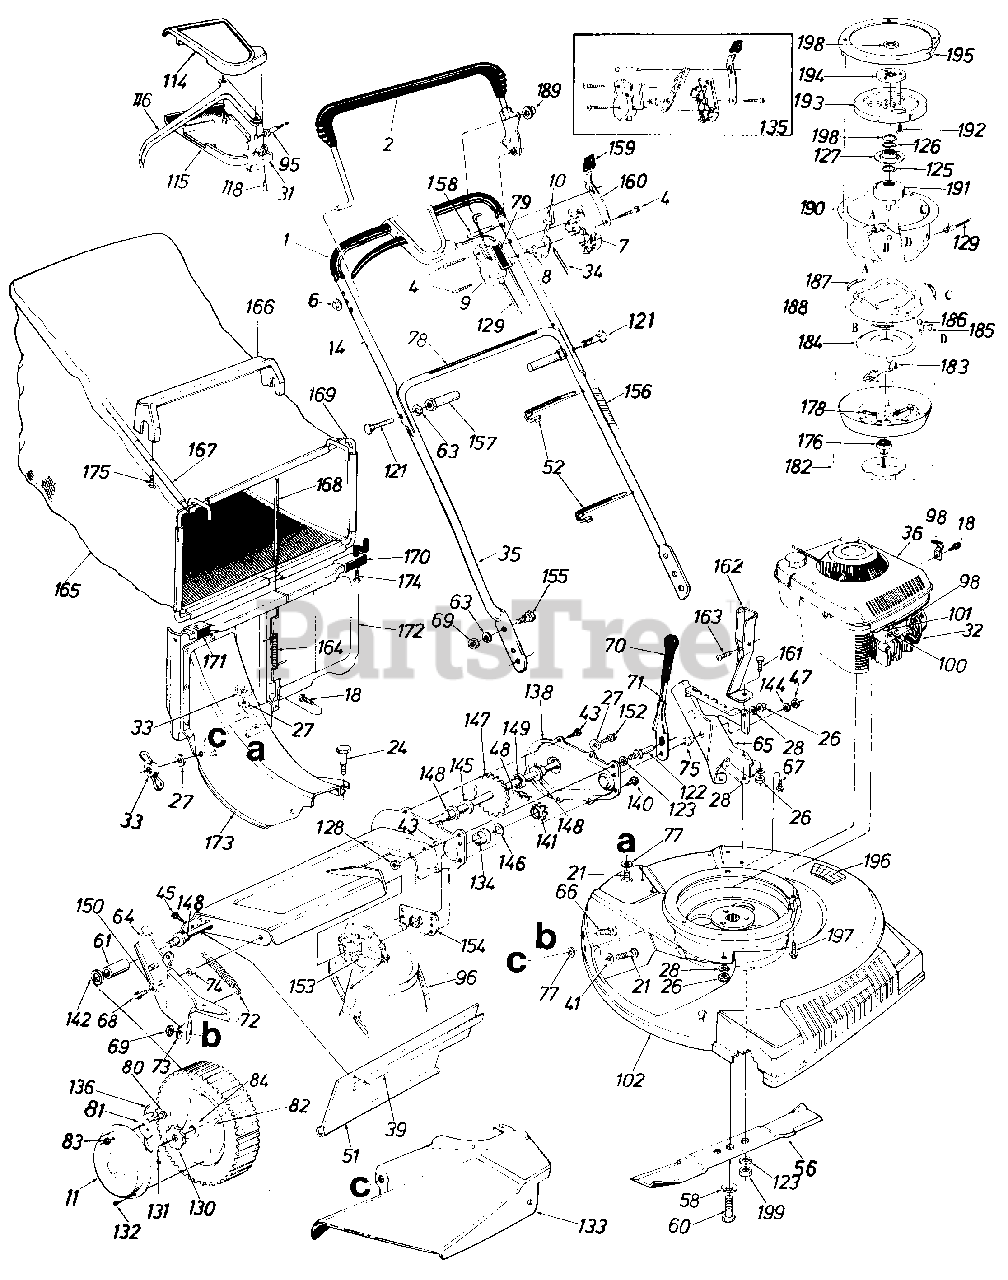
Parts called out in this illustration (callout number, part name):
2	Control Handle Ass'y. L.H.
4	Truss Mach. Scr. #12 x 1.50" Lg.
6	Push Cap
7	Control Panel Half
8	Control Disc Pin
9	Clutch Panel Half
10	Throttle Control Lever
11	Hub Cap
14	Upper Handle Chrome
18	Hex B-Tap Scr. #10 x .38"
21	Carriage Bolt 1/4-20 x .62"
24	Shoulder Bolt .312 Dia. x .18 Lg. Special
26	Hex Nut 1/4-20 Thd.
27	Bell-Wash. 1/4" I.D.
28	L-Wash. 1/4" I.D.
31	S.P. Control Cover
32	Spark Plug Insulator
33	Wing Nut
34	Throttle Control Wire 58"
35	Lower Handle Chrome
36	Engine
39	Retaining Strip
41	Fl-Wash. .344" I.D. x .62"
43	Hex B-Tap Scr. 1/4" x .38"
45	Hex AB-Tap Scr. 1/4 x .62"
47	Hex Patch L-Nut 3/8-24 Thd.
48	#48 Chain .500" Pitch x .30 Links
51	Rear Flap 3.75" x 17.30" Lg.
52	Cable Tie
56	21" Blade
58	Bell-Wash. .460" I.D. x .880"
60	Hex Bolt 7/16-20 x 2.0
61	Spacer.513" I.D.
63	L-Wash. 5/16" I.D.
64	R.H. Handle Wheel Brkt. Ass'y.
65	L.H. Handle Wheel Brkt. Ass'y.
66	Carriage Bolt 5/16-18 x .62"*
67	Hex Wash. Hd. B-Tap Scr. 5/16-18
68	Hex Wash. Hd. TT-Tap Scr. 3/8-16
69	Hex Nut 5/16-18 Thd.
71	Height Adj. Lever
72	Extension Spring 3.80" Lg.
73	Bell-Wash. 5/16" I.D.
74	Spacer.385" I.D.
75	Shld. Spacer.5" Dia.
77	Bolt Retainer 1/4 x .50" O.D.
78	Instruction Label
79	Control Label
80	Shld. Scr. .342" Dia. x .268
81	Pawl
82	Wheel Ass'y. Comp. Rear
83	Hex Ins. L-Nut 1/4-20 Thd.
84	Flange Ball Bearing 1/2" I.D.
95	S.P. Cable x 50" Lg.
96	"V"-Belt
98	Casing Clamp
100	Hex B-Tap Scr. #10 x .62"
101	Casing Clamp
115	Self-Propelled Control Cover
116	Control Lever
118	Fl-"C"-Sunk Hd. Tap Scr. #10 x .75" Lg.
121	Curved Carr. Bolt 5/16-18 x 1.75" Lg.
122	Shld. Pin 1.43" Lg.
123	L-Wash. 3/8" I.D.
125	Serrated Wash. 1.0" I.D.
126	Wave Wash. 1.005" I.D.
127	Serrated Pulley Half
128	Hex Nut 3/8-24 Thd.
129	Clutch Cable 49"
130	Ratchet Wheel 1.62" O.D.
131	Cotter Pin 1/8" Dia. x 1"
132	Pan Hd. Tap Scr. #12 x .50"
133	Side Chute Deflector Ass'y.
134	Flange Bearing
135	Kit Control Housing Comp.
136	Spring Nylon
138	Chain Cover
140	Hex Wash. S-Tap Scr. 1/4-20 x.50" Lg.
141	Sprocket Shaft Ass'y.
142	Fl-Wash. .510" I.D. x 1.0"
144	Fl-Wash. .385" I.D. x 87"
145	Fl-Wash. .51" I.D. x 1.0"
146	Fl-Wash. 3/8" I.D.
147	Rear Shaft Ass'y. 21.94" Lg.
148	Hex Flange Brg. .506" I.D.
149	Fl-Wash. .531" I.D. x .930"
150	Fl-Wash. .531" I.D.
152	Hex Bolt 1/4-20 x .62" Lg. (Grade 5)
153	Transmission Comp.
154	Hex Bearing Cup
155	Truss Mach. Scr. 5/16-18 x .75" Lg.
156	Plastic Tubing
157	Catcher Support Pin
158	Lock Pin .314" Dia. x 1.75"
159	Spring Lever Knob
160	Lockout Spring
161	Hex Bolt 1/4-20 x .50" Lg.
162	Grass Catcher Bracket
163	Truss Mach. Scr. 1/4-20 x .50" Lg.
164	Torsion Spring
165	Grass Bag
166	Bag Handle
169	Front Catcher Frame
170	Door Clip
171	Panel Bag Clip
172	Chute Door
173	Top Discharge Chute Ass'y.
174	Hex AB-Tap Scr. 1/4 X .75"Lg.
175	Truss Mach. B-Tap Scr. #12 X 1.5" Lg.
176	Ball Bearing
178	Compression Spring
182	Clutch Blade Housing Ass'y.
183	Hex Wash. TT-Tap Scr 1/4-20 X .75" Lg.
184	Brake Cup Cone
185	Ball Block
186	Steel Ball
187	Ext. Spring 1.75" Lg.
188	Clutching Cone
189	Push Cap
190	Clutch Housing
191	Fixed Pulley Adapter
192	Flat Hd. B-Scr. 1/4-20 x .62"Lg.
193	Flywheel
194	Flywheel Adapter
195	Engine Mtg. Cover Plate Ass'y.
196	Rubber Foot Pad
197	Hex Wash. Hd. Tap Scr. 3/8-16 x 1.50" Lg.
198	Serrated Wash. 1.0" I.D.
199	Hex Nut 3/8-24 Thd. (Grade 8)
